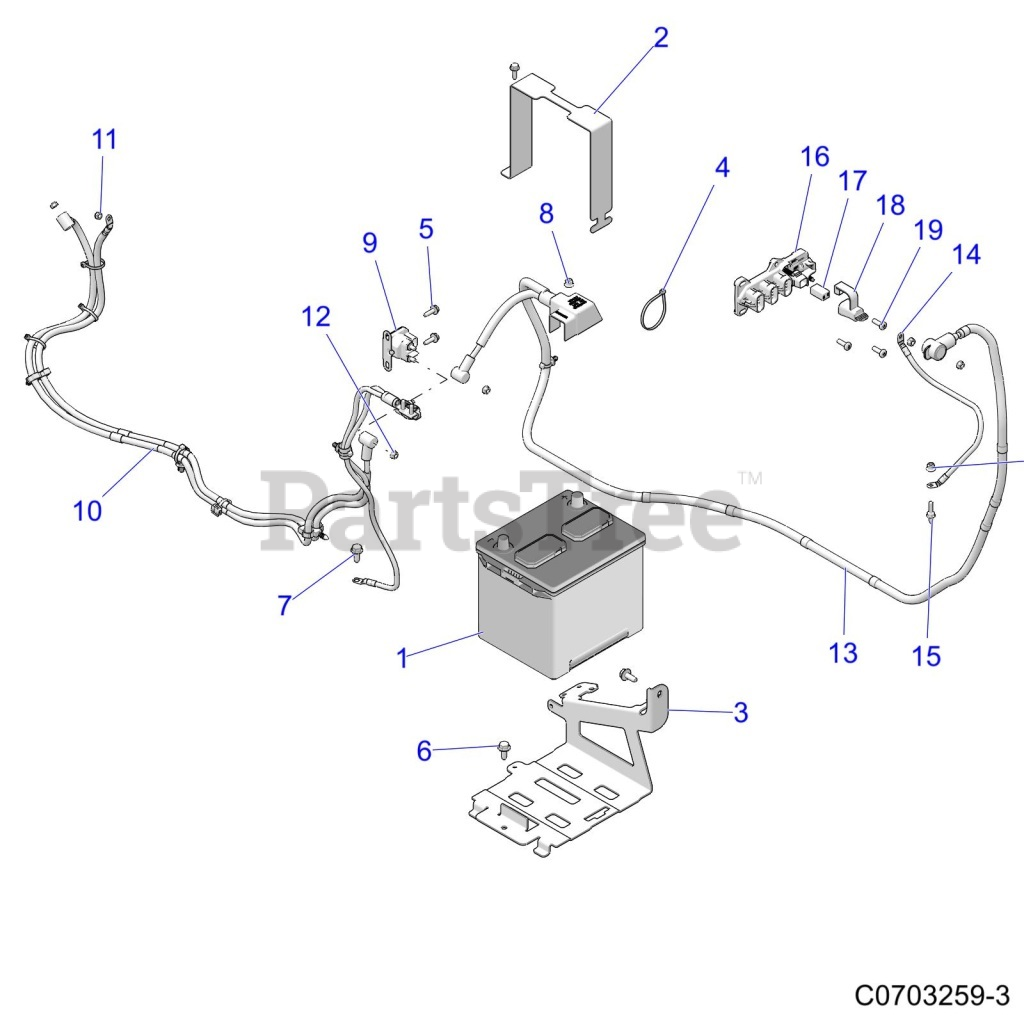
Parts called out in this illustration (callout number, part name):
1	BATTERY-575 CCA,FLOODED,FILLED
2	BRKT-BATTERY STRAP GALV
3	BRKT-BATTERY TRAY,BLK
4	CABLE TIE (10)
5	SCR-M6X1.0X20,HXHD,FLG,TDFM,BL
6	BOLT-M8X1.25X20,HXFLG,TAP/R-OD
7	SCR-HXFL-M8X1.25X20 TAP ZY3
8	NUT-M6 FLANGE,NYLOK
9	SOLENOID-STARTER,SEALED
10	CABLE-START,TO,SOLENOID,GAS
11	NUT,NYLOK(10)
12	NUT-HXFLGHD,M6,SERRATED
13	CABLE-BATTERY TO SOLENOID
14	CABLE-BAT TO GND
15	STUD-M6X1.0X19-M6 TAPTITE
16	BLOCK-TERMINAL,3 POS
17	FUSE-CARTRIDGE,25A
18	COVER,TB,25A,JCASE
19	SCR-TXPH-#14 X .75 HI-LO RIE
